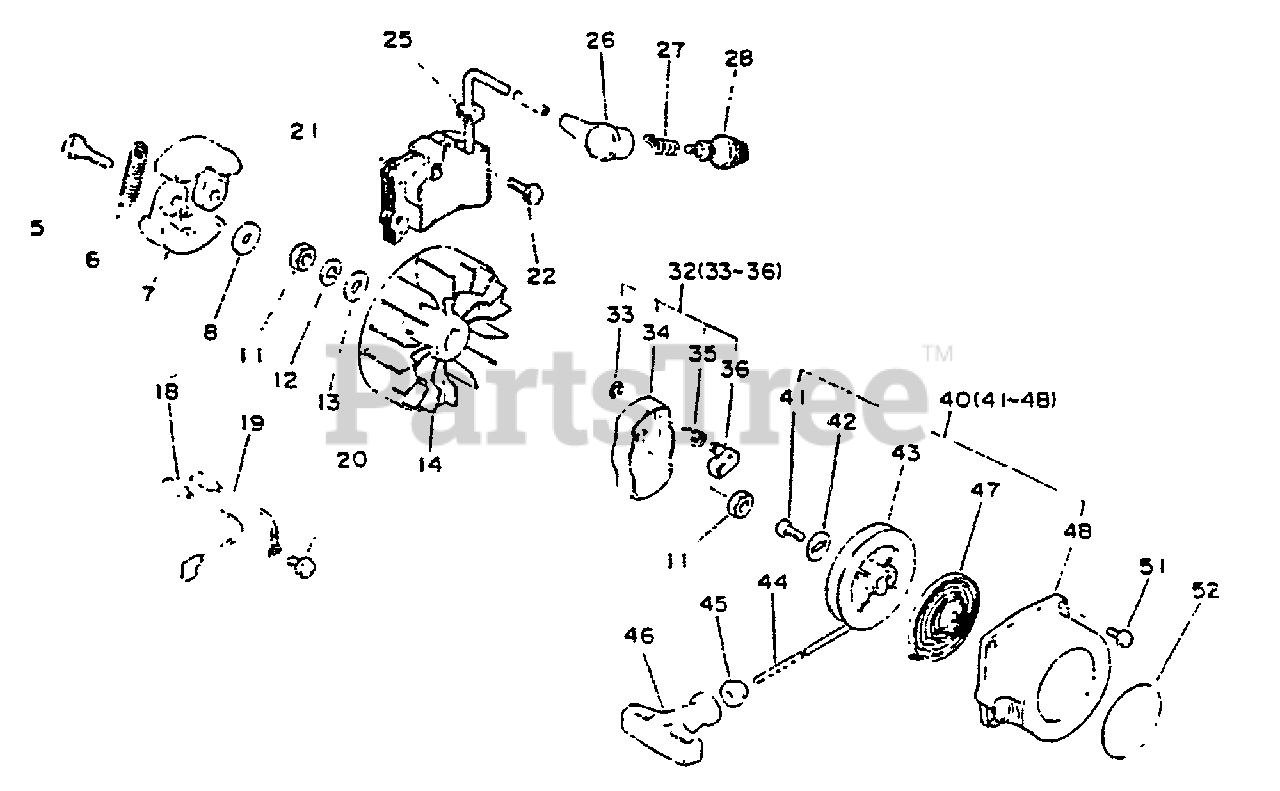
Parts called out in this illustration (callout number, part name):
5	BOLT, CLUTCH
6	SPRING, CLUTCH
7	SHOE, CLUTCH
8	WASHER 6.2×19×1.0
11	NUT 8×1.25
12	WASHER, SPRING 8
13	WASHER 8.5×16×1.2
14	FLYWHEEL
18	LEAD
19	LEAD - GROUND
20	SCREW 5×10
21	COIL, IGNITION
22	SCREW 5×20
26	CAP, SPARK PLUG
27	TERMINAL, SPARK PLUG
28	SPARK PLUG - CJ-7Y
32	PAWL ASSY, STARTER
33	E-RING 4
34	CATCHER, PAWL
35	SPRING, RETURN
36	PAWL, STARTER
40	STARTER ASSY
42	WASHER
43	REEL, ROPE
44	ROPE, STARTER
45	GUIDE, ROPE
46	GRIP, STARTER
47	SPRING, RECOIL
48	CASE, RECOIL STARTER
51	SCREW 4×14
52	LABEL - ECHO
